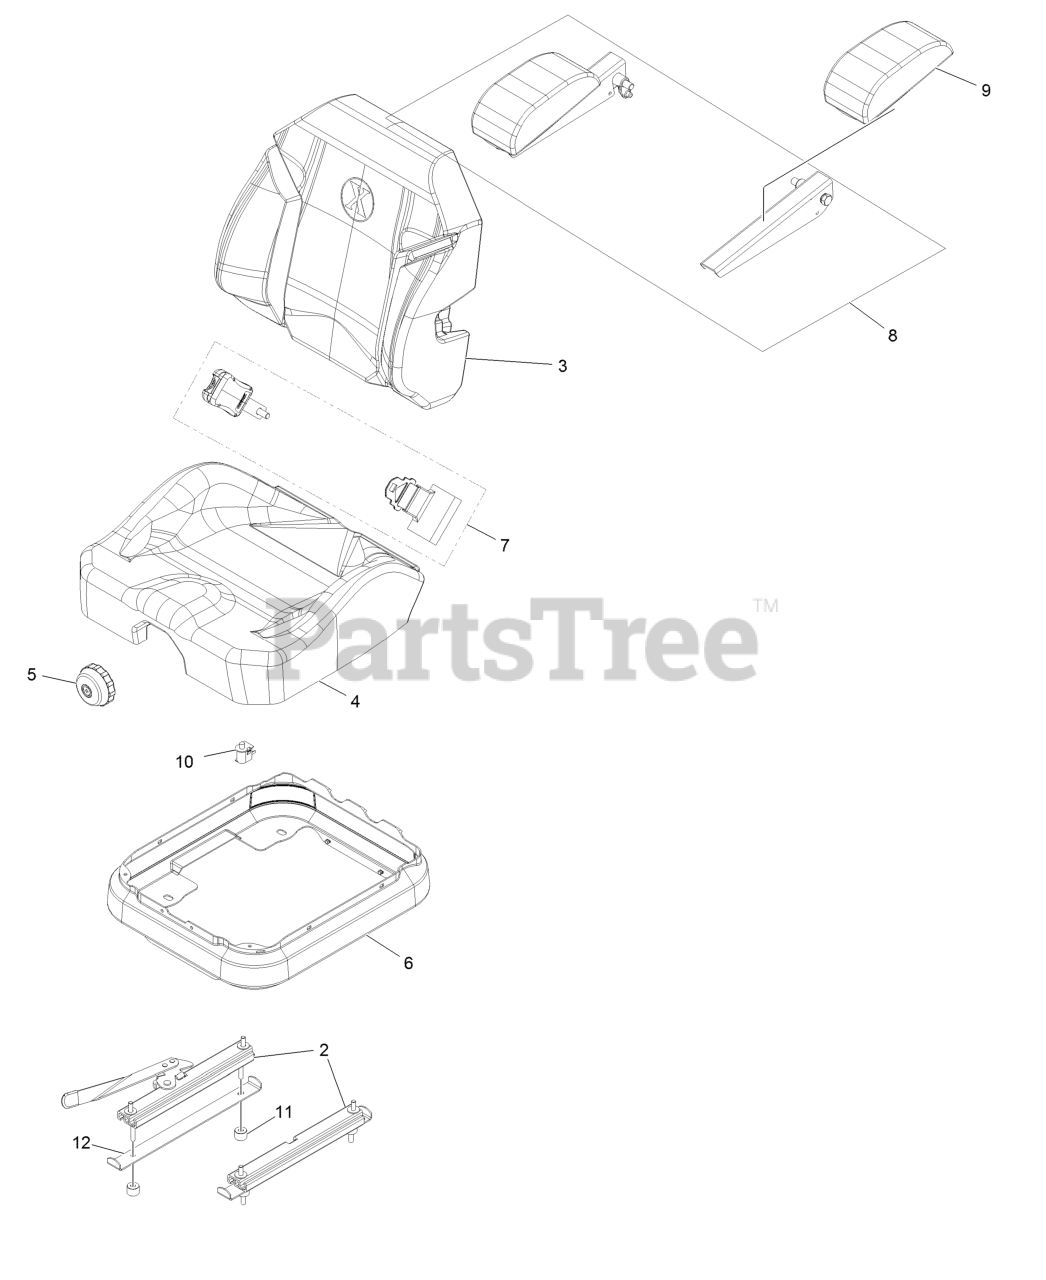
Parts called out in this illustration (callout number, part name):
2	Seat Track Set
3	Cover-Back 311463Vn500
4	Cover-Cushion 311464Vn500
5	Knob-Adjuster
6	Cover-Suspension Bellows
7	Seat Belt Service Kit
8	Kit-Arm Rest Set
9	Kit-Arm Rest Pads
12	Stop, Seat
